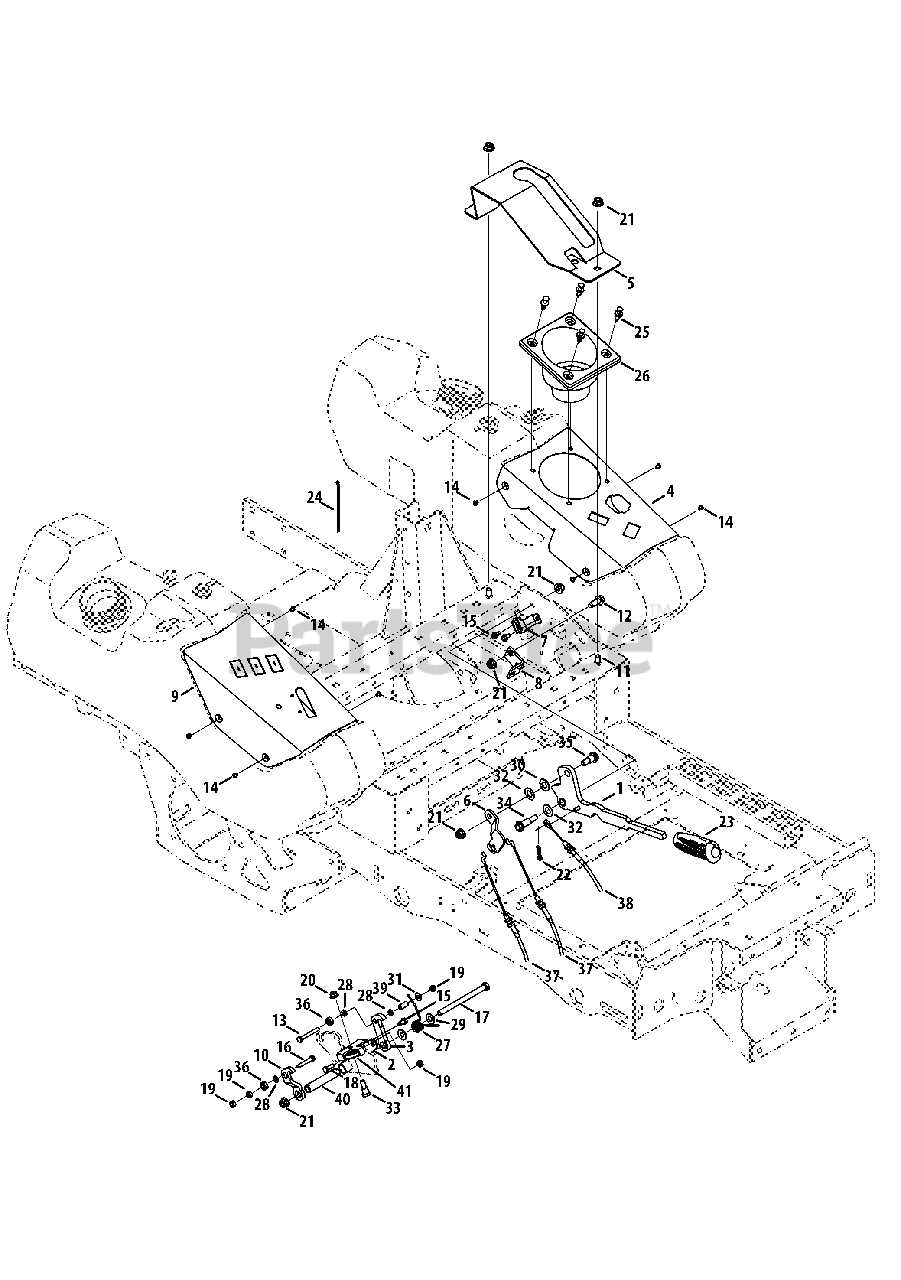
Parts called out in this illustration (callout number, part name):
1	Brake Handle Weldment
2	Brake Control Bracket Assembly
3	Lock Control Plate
4	LH Control Panel
5	Boot Brake Bracket
6	Pivot Brake Bracket
7	Brake Switch Bracket
8	Lockout Cable Mounting Bracket
9	RH Control Panel
10	Lock Control Plate
11	Carriage Bolt, 3/8-16 x .75
12	Screw, 3/8-16 x 1.00
13	Hex Cap Screw, 1/4-20 x 2.00
14	Machine Screw, #10-32 x .25
15	Hex Flange Screw, 1/4-20 x .500
16	Carriage Screw, 1/4-20 x 1.50
17	Hex Cap Screw, 3/8-16 x 5.00
18	Hex Cap Screw, 1/4-20 x .75
19	Nut, 1/4-20, Hexlock
20	Nut, 5/16-18, Flangelock
21	Nut, 3/8-16, Flangelock
22	Bow Tie Cotter Pin
23	Grip, .50 ID
24	Cable Tie
25	Rivet, .3125
26	Cup Holder
27	Torsion Spring, .70 ID
28	Washer, .281 x .500 x .063
29	Washer, .385 x .87 x .06
30	Washer, .510 x 1.00 x .060
31	Washer, .250 x .630 x .052
32	Washer, .531 x 1.00 x .030
33	Shoulder Screw, .437 x .470, 5/16-18
34	Shoulder Bolt, .50 x .925, 3/8-16
35	Shoulder Screw, .50 x .50, 3/8-16
36	Ball Bearing, .250 x .625
37	Brake Cable
38	Brake Lockout Cable
39	Spacer, .260 x .375 x .75
40	Spacer, .385 x .625 x 3.293
41	Roller Cable Pulley, 1.69 Dia.
